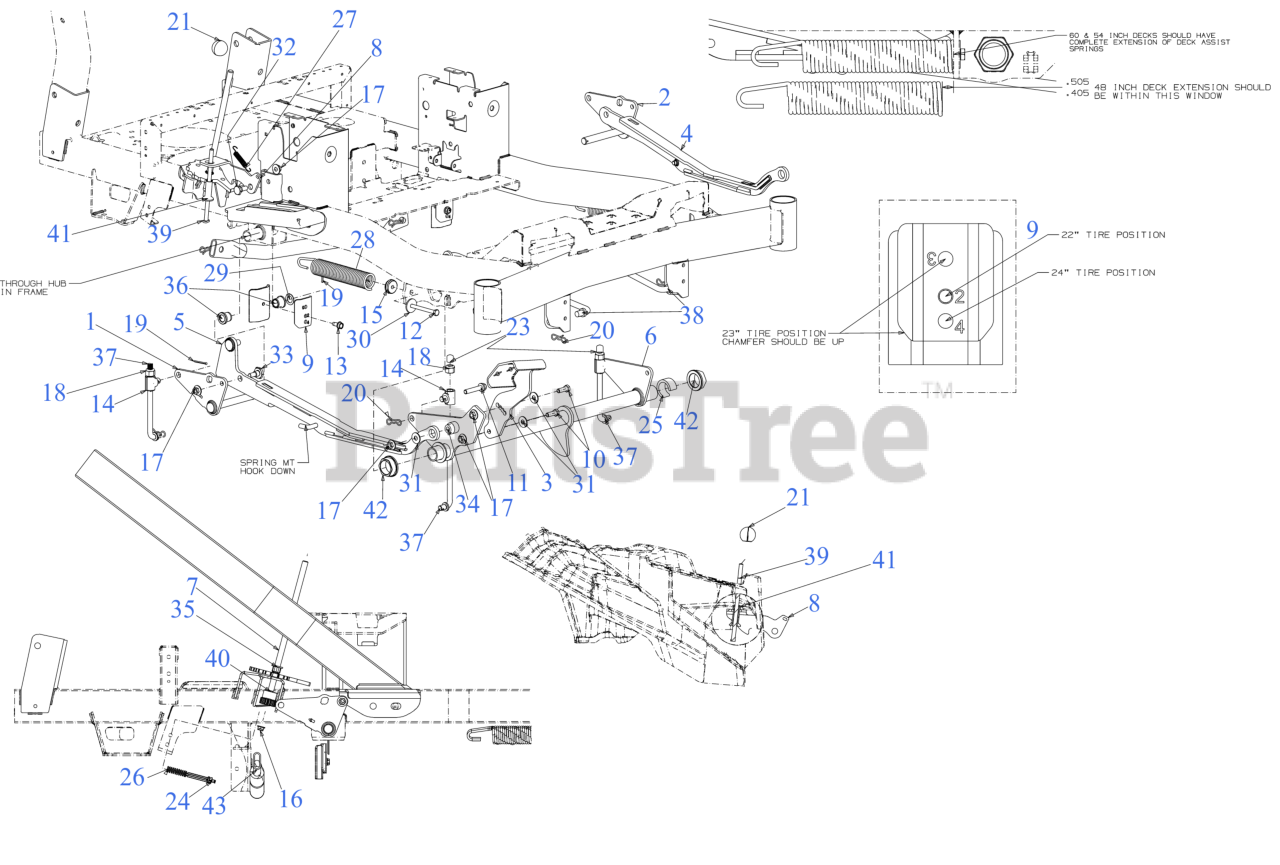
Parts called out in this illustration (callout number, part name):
1	BELLCRANK BRACKET (RH)
2	BELLCRANK BRACKET (LH)
3	DECK LIFT PEDAL
4	LIFT LINK (LH)
5	LIFT LINK (RH)
6	LIFT TUBE (FRONT)
7	DECK HEIGHT ADJUSTMENT ROD
8	TRAVEL LOCK PLATE
9	UPSTOP BRACKET
10	SCREW 3/8-16 x 1 GR5
11	SCREW 3/8-16 x 2.00 GR5
12	SCREW 5/16-18 x 3.50 GR5
13	SCREW 5/16-18 x .750
14	LIFT ROD FERRULE
15	LIFT SPRING INSERT
16	FLANGE LOCK NUT 5/16-18
17	FLANGE LOCK NUT
18	HEX LOCK NUT NYLON
19	COTTER PIN
20	BOW TIE COTTER PIN
23	LIFT ROD END CAP
24	DETENT PLUNGER
25	LIFT TUBE SPACER
26	COMPRESSION SPRING .531 OD 1.75 LG
27	EXTENSION SPRING 2.675"
28	EXTENSION SPRING
29	FLAT WASHER
30	WASHER-5/16 x 1.25X 1.27
31	WASHER-.395 x 1.0 x .62
32	SHOULDER SCREW
33	SHOULDER SCREW .50 x .385
34	SHOLUDER SPACER
35	HEX FLANGE BEARING .506ID x .590LG
36	FLANGE BUSHING
37	DECK LIFT ROD 6.875"
38	DECK CONTROL ROD
39	TRAVEL LOCK ROD
40	DECK HEIGHT DETENT HUB
41	LOCK ROD SLEEVE SPACER
42	FLANGE BEARING
43	DECK STABILIZER TUBE
